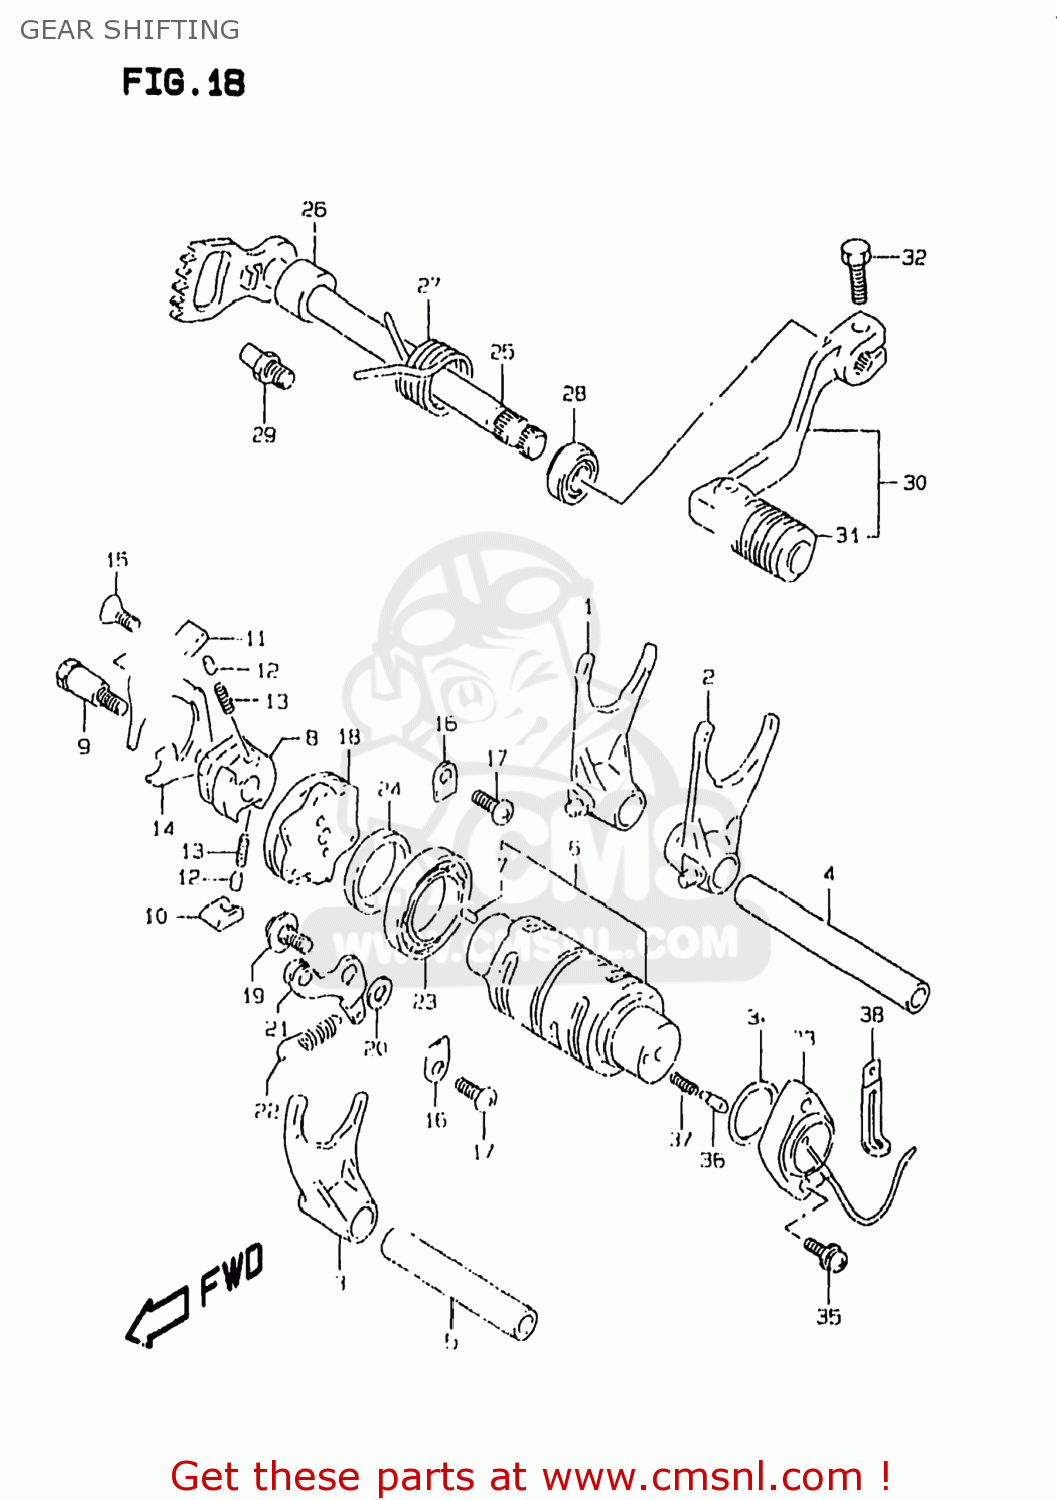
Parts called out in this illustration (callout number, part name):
1	FORK,GEAR SHIFT NO.1
2	FORK,GEAR SHIFT NO.2
3	FORK,GEAR SHIFT NO.3
4	SHAFT,GEAR SHIFT FORK
5	SHAFT,GEAR SHIFT FORK(L:70)
6	CAM,GEAR SHIFT
7	PIN
8	GEAR,GEARSHIFT CAM DRIVE
9	PIN,SHIFT CAM DRIVEN GEAR
10	PAWL,GEAR SHIFT NO.1
11	PAWL,GEAR SHIFT NO.2
12	PIN(5X8)
13	SPRING
14	LIFTER,GEAR SHIFT PAWL
15	SCREW
16	RETAINER
17	SCREW
18	PLATE,GEAR SHIFT CAM
19	BOLT(6X14.3)
20	WASHER
21	STOPPER,GEAR SHIFT CAM
22	SPRING
23	BEARING
24	WASHER(25X32X5.3)
25	SHAFT,GEAR SHIFT
26	SPACER(12X20X15.3)
27	SPRING
28	OIL SEAL
29	STOPPER,GEAR SHIFT ARM
30	LEVER ASSY,GEAR SHIFT
31	RUBBER,GEAR SHIFT PEDAL
32	BOLT
33	BASE ASSY,NEUTRAL SW TERMINAL
34	O RING(D:2.4,ID:26.2)
35	SCREW
36	PIN(5X15.5)
37	SPRING
38	CLAMP(L:45)
